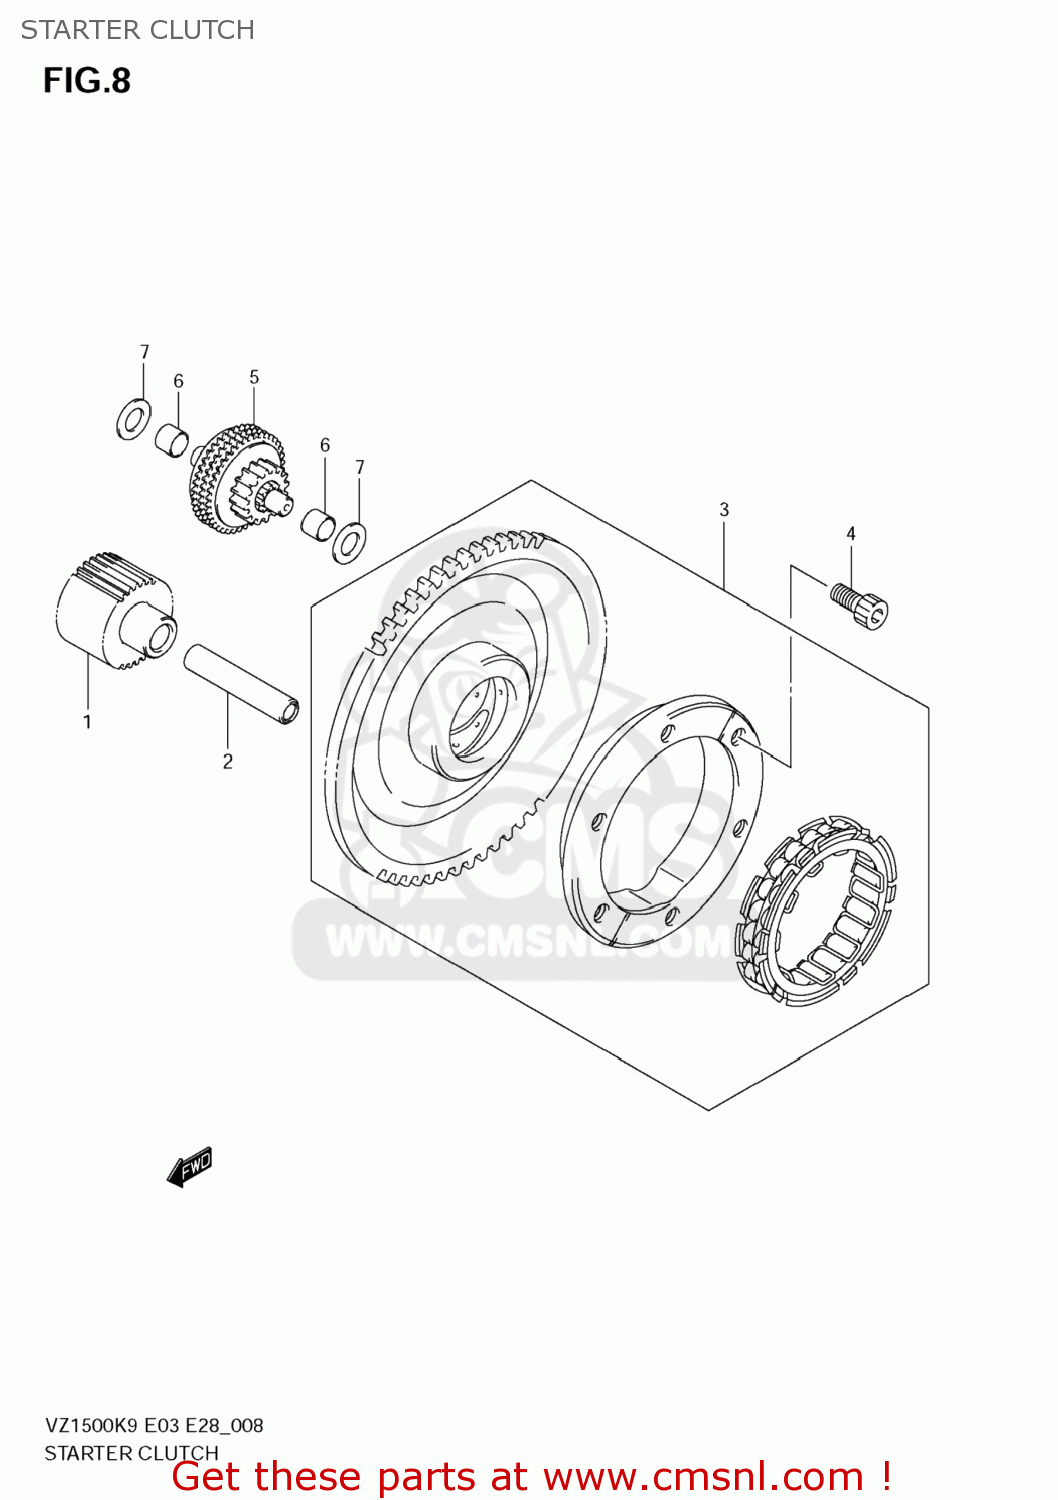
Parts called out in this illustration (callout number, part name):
1	GEAR,STARTER IDLE NO.1
2	PIN(7X11X55)
3	CLUTCH SET,STARTER(NT:78)
4	BOLT(8X16)
5	LIMITER ASSY,START ID GR NO.2
6	BUSH,LIMITER GEAR SHAFT
7	SHIM(10X20X1)
